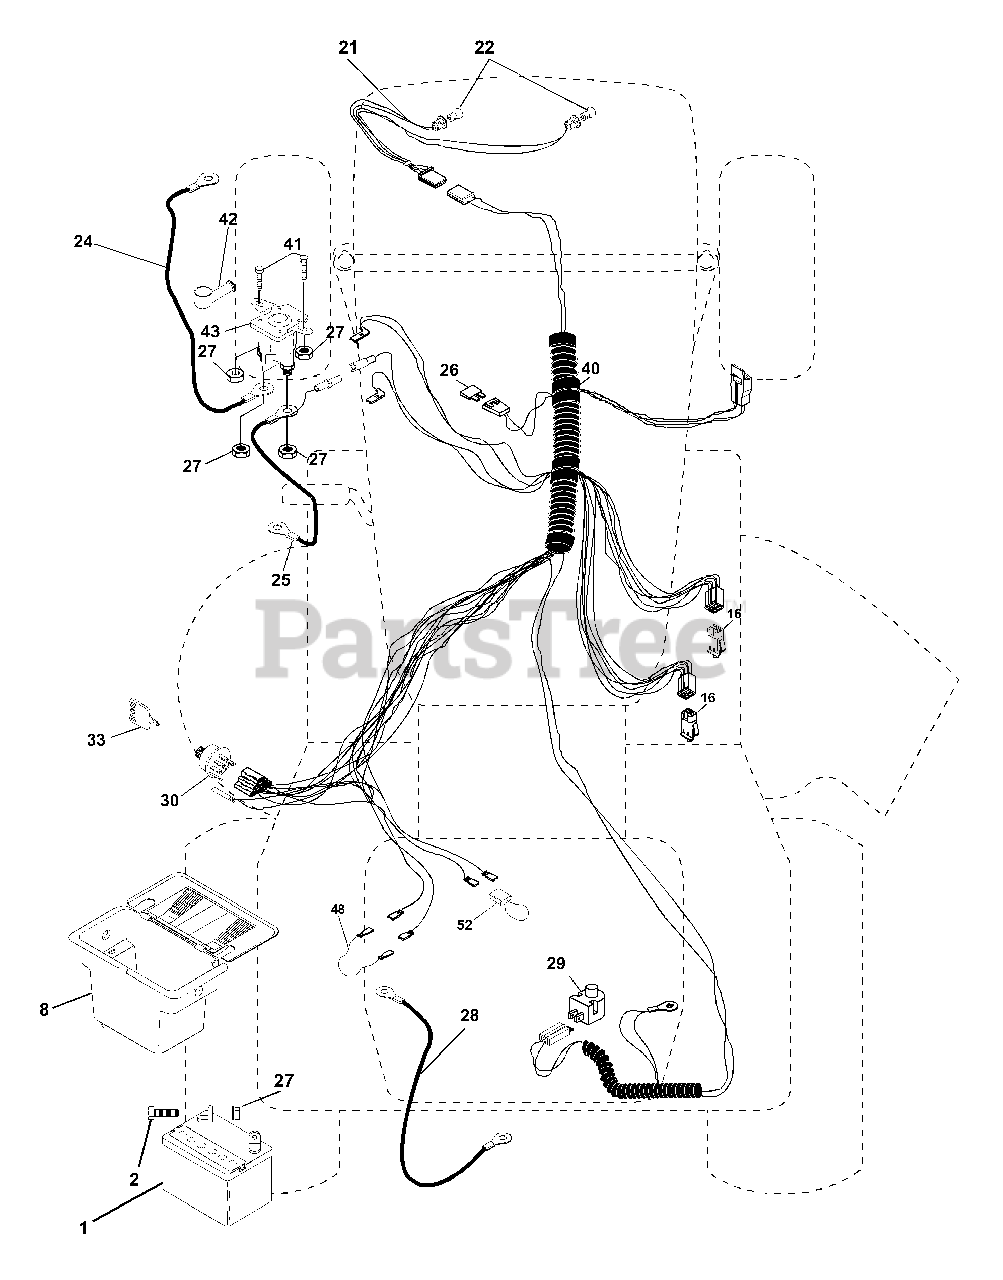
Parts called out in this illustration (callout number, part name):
1	Battery
2	Bolt Hex Hd 1/4-20unc X 3/4
8	Case Battery
16	Switch Interlock Push-In
21	Harness Socket Light W/4152J
22	Bulb Light #1156
24	Cable Battery 6ga 161" red
25	Cable Battery 6 Ga W/16 Wir red
26	Fuse 15 AMP
27	Nut Keps Hex 1/4-20 Unc
28	Cable Ground 6ga 12" black
29	Switch Plunger Nc Gray
30	Switch Ign
33	Key Ign
40	Harness Ign
41	Bolt Blk Hex 1/4-20unc x 1/2
42	Cover Terminal Red
43	Solenoid
48	Adapter Ammeter Rectangular
52	Protection Wire Loop
